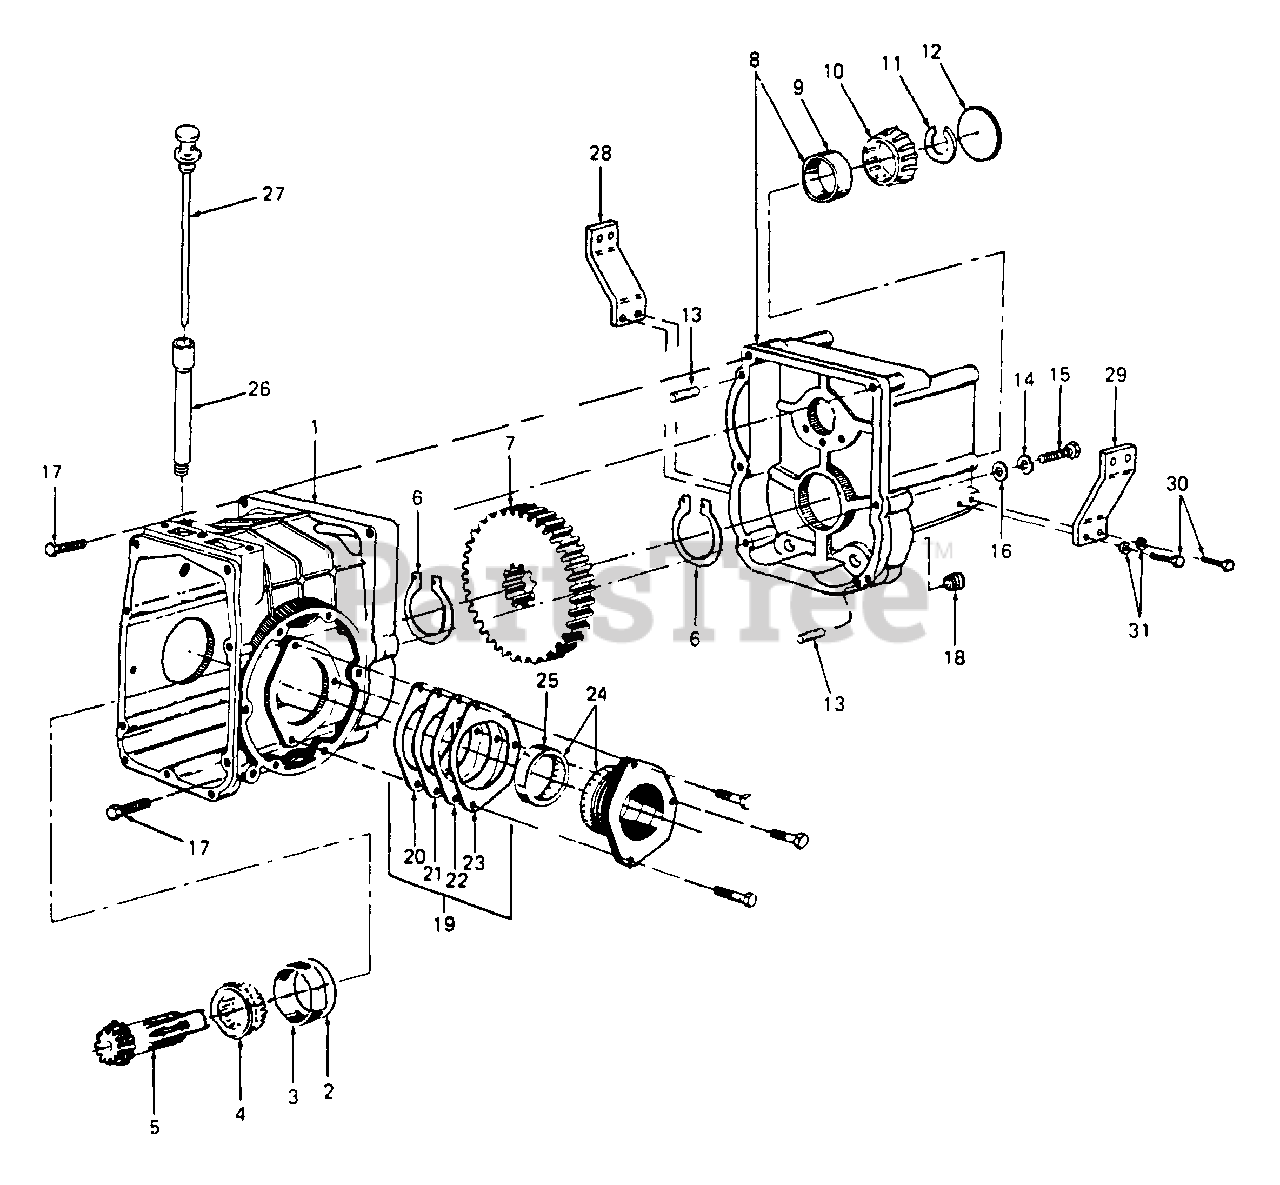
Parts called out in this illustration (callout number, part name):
1	Housing Assy, Rear Transaxle
2	Shim, Rear Bearing Cup, .004 Thk
3	Cup, Roller Bearing
4	Cone, Roller Bearing
5	Shaft, Bevel Pinion
6	Ring, Retaining, 1.312 Dia
7	Gear, Reduction - 68T
8	Housing Assy, Adapter w/Cup
9	Cup, Roller Bearing
10	Cone, Roller Bearing
11	Retainer, Front Bearing, .125 Thk
12	Plug, Expansion, 2.12 OD
13	Pin, Dowel, 3/8 Dia x 5/8 Lg
14	Washer, Spring, .445 x .75 x .017 Thk
15	Screw, Hex Cap, 7/16-14 x 2.5 Lg GR5
16	Washer, Flat, .46 x .875 x .060 Thk
17	Bolt, Hex Patch, 7/16-14 x 1.75 Lg GR5
18	Plug, Drain
19	Shim Package
20	Shim, Bearing Retainer, .004 Thk
21	Shim, Bearing Retainer, .007 Thk
22	Shim, Bearing Retainer, .014 Thk
23	Shim, Bearing Retainer, .028 Thk
24	Retainer Assy, Bearing w/Cup
25	Cup, Roller Bearing
26	Tube, Dipstick
27	Blade Assy, Dipstick
28	Bracket, Trans Mtg - LH
29	Bracket, Trans Mtg - RH
30	Bolt, Hex Patch, 3/8-16 x 1.0 LG GR5
31	Washer, Lock, 3/8
